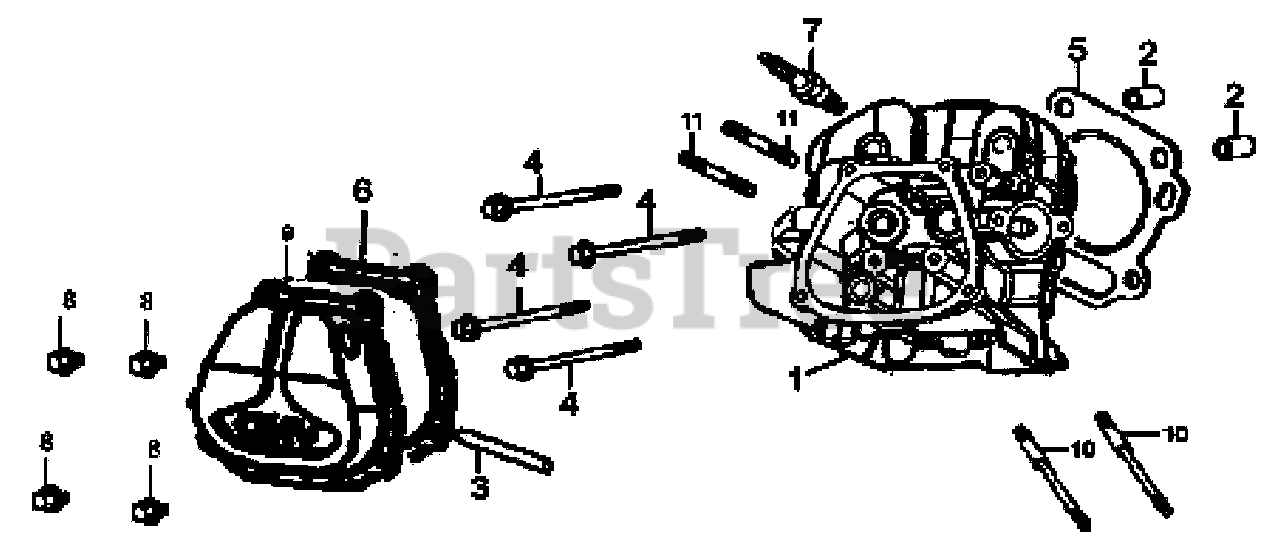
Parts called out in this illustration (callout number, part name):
1	HEAD COMP., CYLINDER
2	PIN, DOWEL
3	TUBE, BREATHER
4	BOLT, FLANGE
5	GASKET, CYLINDER
6	PACKING, HEAD COVER
7	PLUG, SPARK
8	BOLT, FLANGE
9	COVER COMP., HEAD
10	BOLT, STUD, INTAKE
11	BOLT, STUD, EXHAUST
